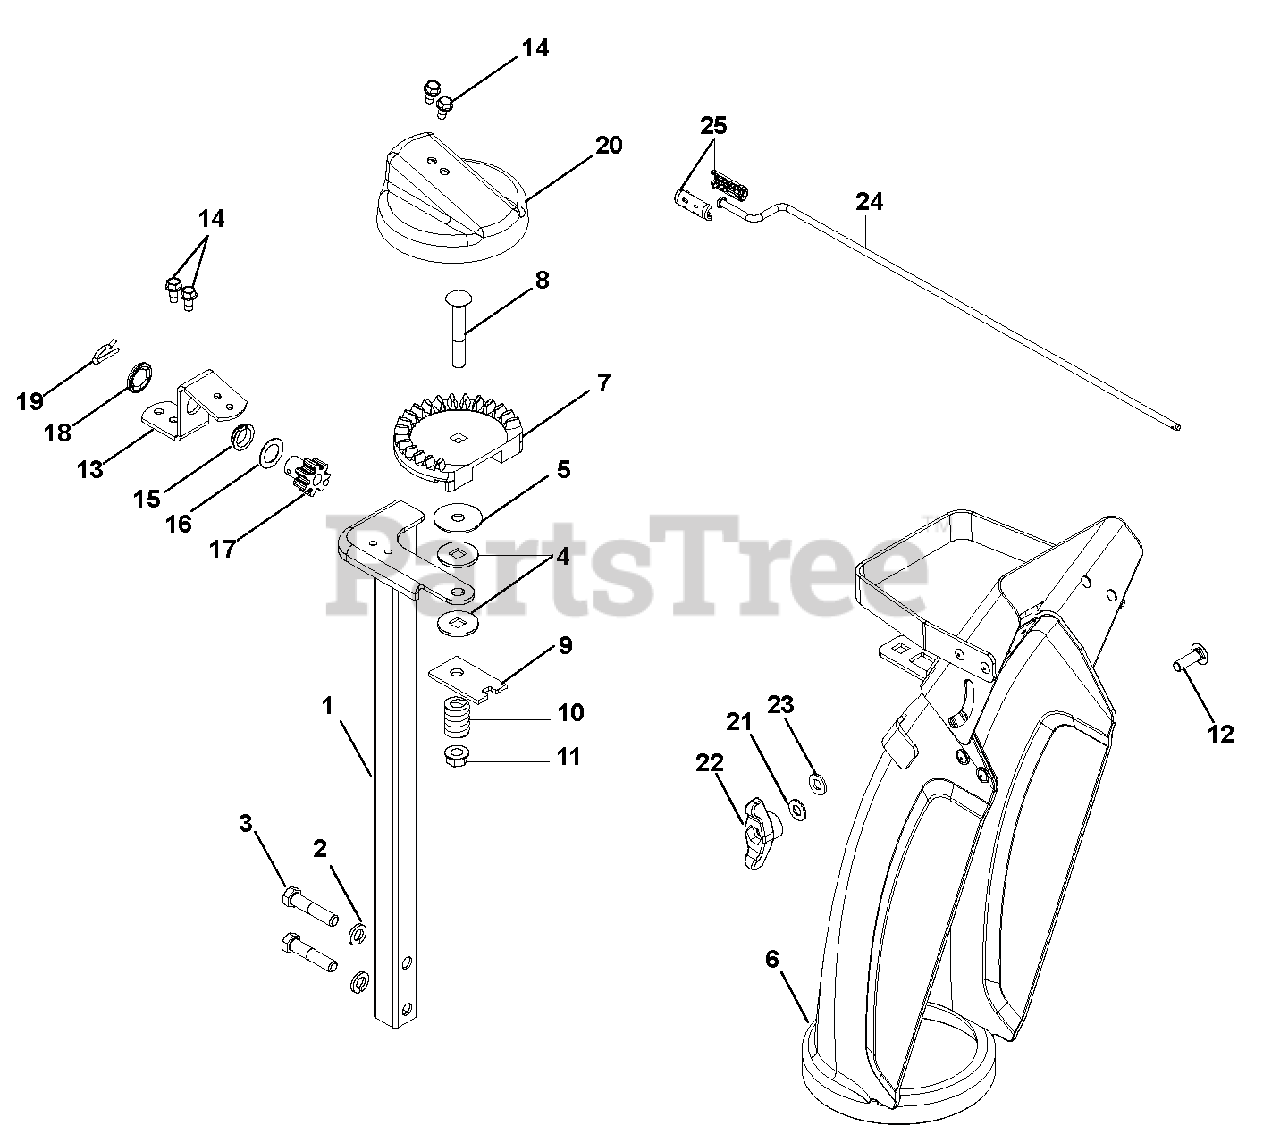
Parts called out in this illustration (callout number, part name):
1	CHUTE PEDESTAL, TALL COMPACT
2	@WSHR-LK .38X.094 REG YWZC
3	@BLT-HEX .38-16X1.75 GR5 YWZC
4	FRICTION WASHER
5	@WSHR-FL-STL .406X1.25X.10 ZC
6	CHUTE, DISCHARGE W/CAP & DECAL
7	CHUTE GEAR
8	@BLT-RDHDSQNK .38-16X2.50 G5YZ
9	PLATE, FRICTION
10	SG-COMP .187X.56X1.62
11	@NUT-LK-TOP-FLG .38-16 YWZC
12	@BLT-RHDSSQNK .31-18X1.00 G5YZ
13	BRACKET, PINION GEAR
14	SCR-TAP .25-20X.50 HWH TR YWZ
15	BUSHING, POLYLINER-.63 SNAPIN
16	WSHR-THRST .625 X 1.0 X .03
17	PINION GEAR W/BRACKET
18	PUSHNUT .625
19	PIN, SPRING CLIP
20	GEAR COVER
21	@WSHR-FL-STL.344X.688X.065YWZC
22	KNOB,WING .31-18 UNC NYL/TALC
23	WSHR-FL-NY .375X.75X.060
24	ROD, CHUTE CRANK - SINGLE SPD
25	KNOB, CHUTE CRANK - SNAP BLK
